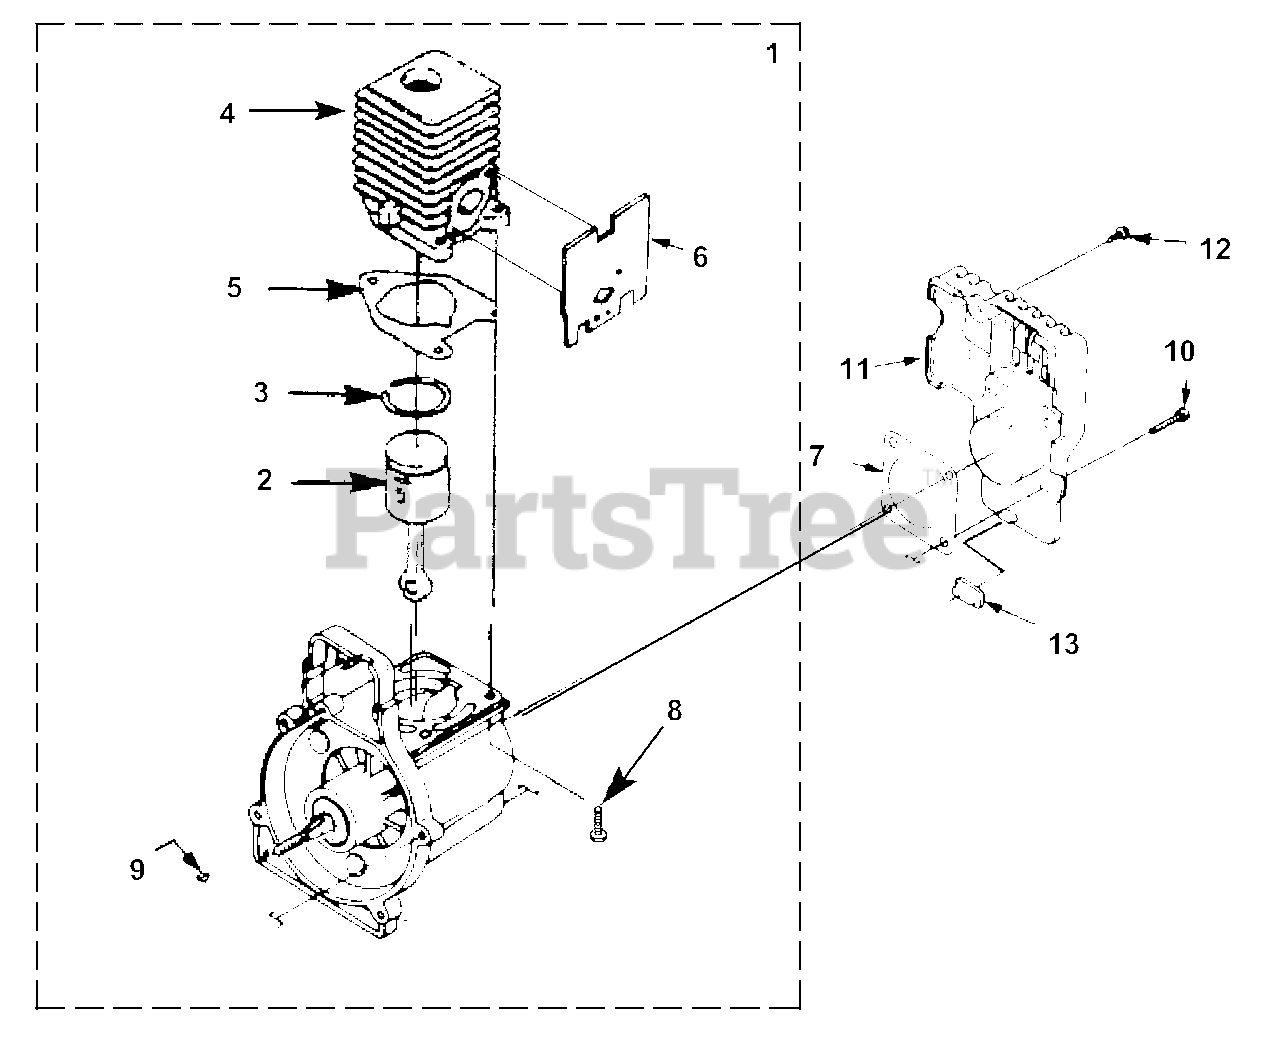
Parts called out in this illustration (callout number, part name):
1	SHORT BLOCK
2	PISTON & ROD
3	RING-Piston
4	CYLINDER KIT
5	GASKET-Cylinder
6	GASKET-Heat Dam
7	GASKET-Crankcase Cover
8	SCREW, SEMS (12-24 x .750)
9	KEY-Woodruff
10	SCREW, SEMS (10-24 x .910)
11	CRANKCASE COVER
12	SCREW-Plastite (#10 X 1/2")
13	BUMPER, Rubber
